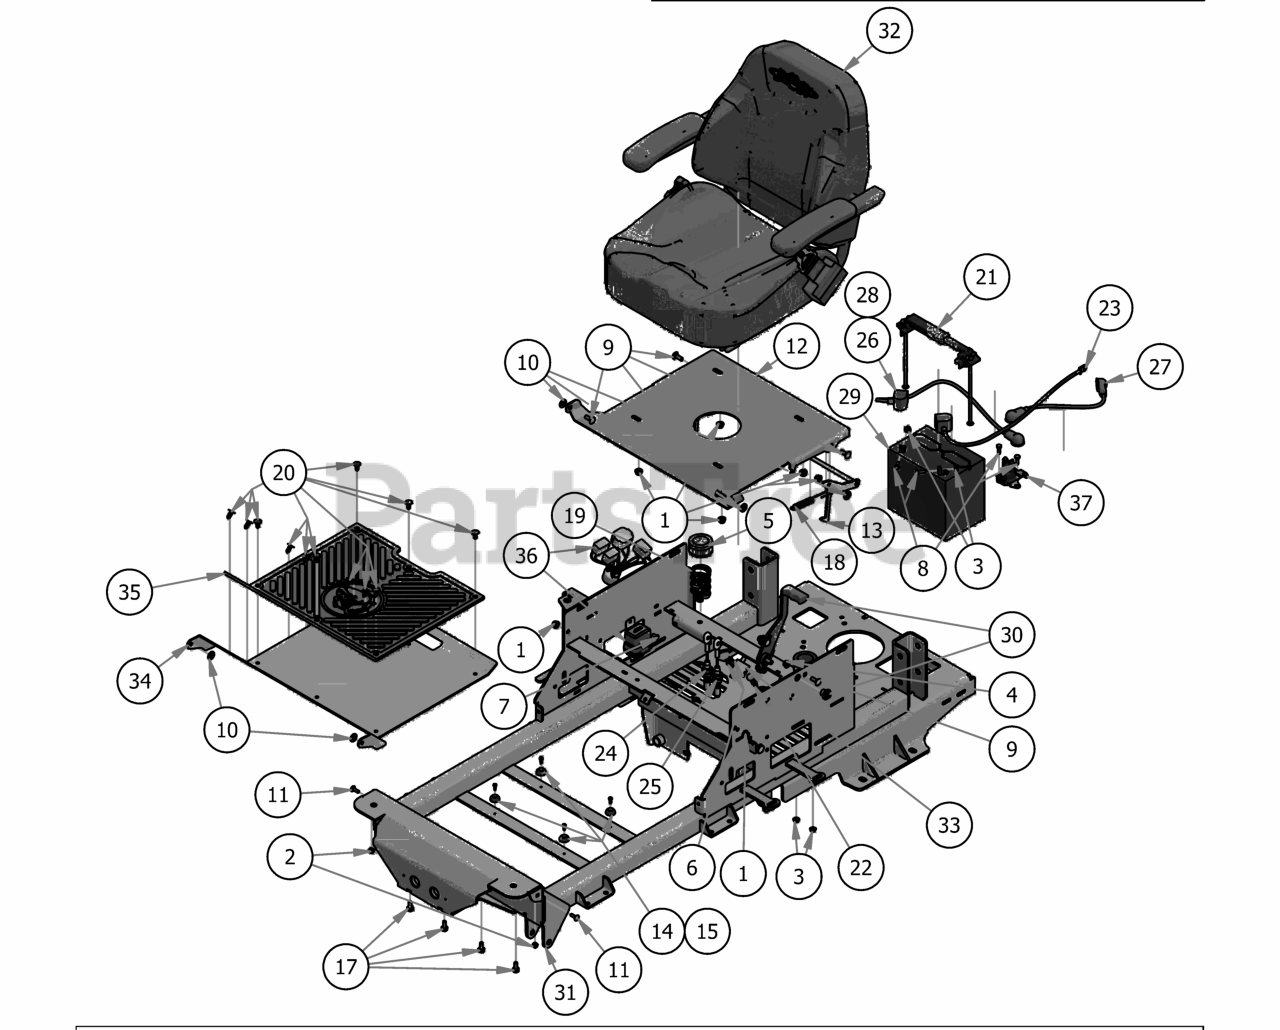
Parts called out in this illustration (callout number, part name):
1	5/16" Nylock Flange Nut
2	1/4" Nylock Nut
3	1/4-20 Hex Flange Nuts Zinc w/Serrations
4	5/16" Flange Nut
5	Seat Spring Cap Cover
6	12-24x 1/2 HWH Bolt
7	1/4" x 1/2" BS C/S 18-8 SS
8	1/4" x 3/4" Hex Bolt
9	5/16" x 7/8" Carriage Bolt
10	.360 ID Plastic Washer
11	1/4" x 3/4" Carriage Bolt
12	Seat Plate 2016
13	Seat Latch Rod Assembly
14	Button Bumper
15	#10 x 1/2" Self Tapping Screw
17	5/16 x 3/4 washer head type F screw
18	Seat Latch Spring
19	Seat Spring Assembly
20	Ratchet Fastener
21	Hold Down Assembly
23	Ground Cable
24	Brake Cable,18.5"
25	Brake Cable, 24.5"
26	24" Red Battery Cable
27	12" Red Battery Cable (Not on Honda)
28	36" Red Battery Cable (Honda Only)
30	2017 ZT Brake Handle Assembly
31	2016 Frame
32	2019 Maverick Seat
33	Safety Switch
34	2018 Maverick Floorboard
35	2017 MZ/ZT Floor Mat
36	Wiring Harness
37	Solenoid (Not used on Honda)
